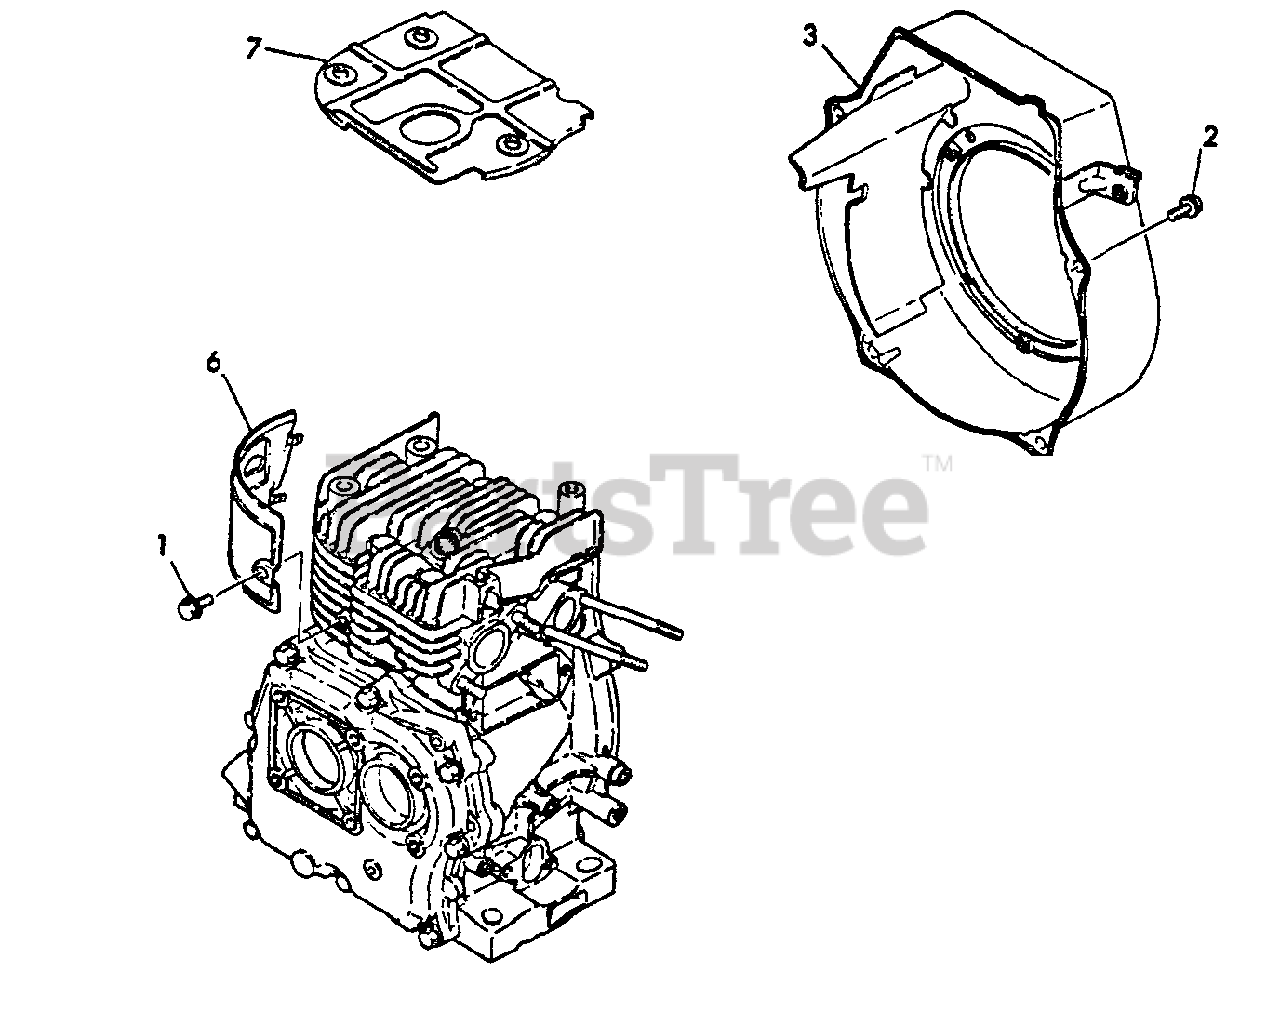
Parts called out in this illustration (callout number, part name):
1	BOLT - 6×8 -- PLATED
2	BOLT - 6×8 -- PLATED
3	COVER, FAN
6	PLATE
7	COVER, HEAD
